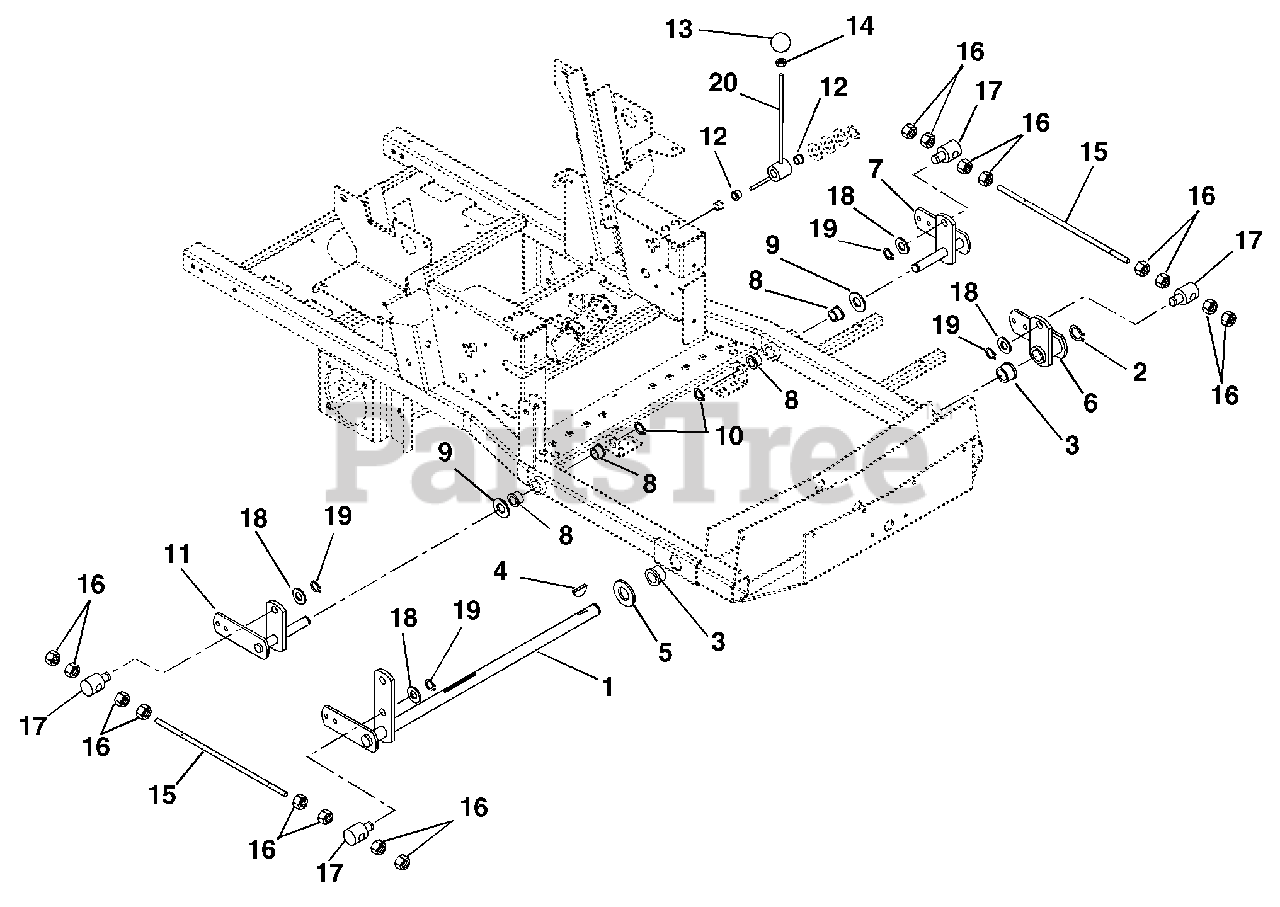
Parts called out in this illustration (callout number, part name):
1	Lift-Mower
2	Ring-Retaining-External 1.00 x .078
3	Bushing-Flange-Nylon 1.020 x 1.385 x .75 x 1.75
4	Key-Woodruff .25 x 1.00
5	Washer-Flat-Steel 1.063 x 2.00 x .134
6	Weldment, Lift Arm-Front
7	Weldment, Lift Arm-Shaft-Left Hand
8	Bushing-Flange-Nylon .762 x 1.0 x .580 x 1.48
9	Washer-Hardened-Steel .758 x 1.23 x .031
10	Ring-Retaining-External .689 x .077
11	Weldment, Lift Arm Shaft-Right Hand
12	Bushing-Flange .63 x 1.00 x .625
13	Knob-Steering Lock
14	Nut-Hex-Jam .375 -16
15	Rod-Lift Assist
16	Nut-Jam .50-13
17	Pivot-Mower Lift
18	Washer-Flat-Steel .630 x 1.005 x .062
19	Ring-Retaining-External .625 x 050
20	Lever-Deck Lift
